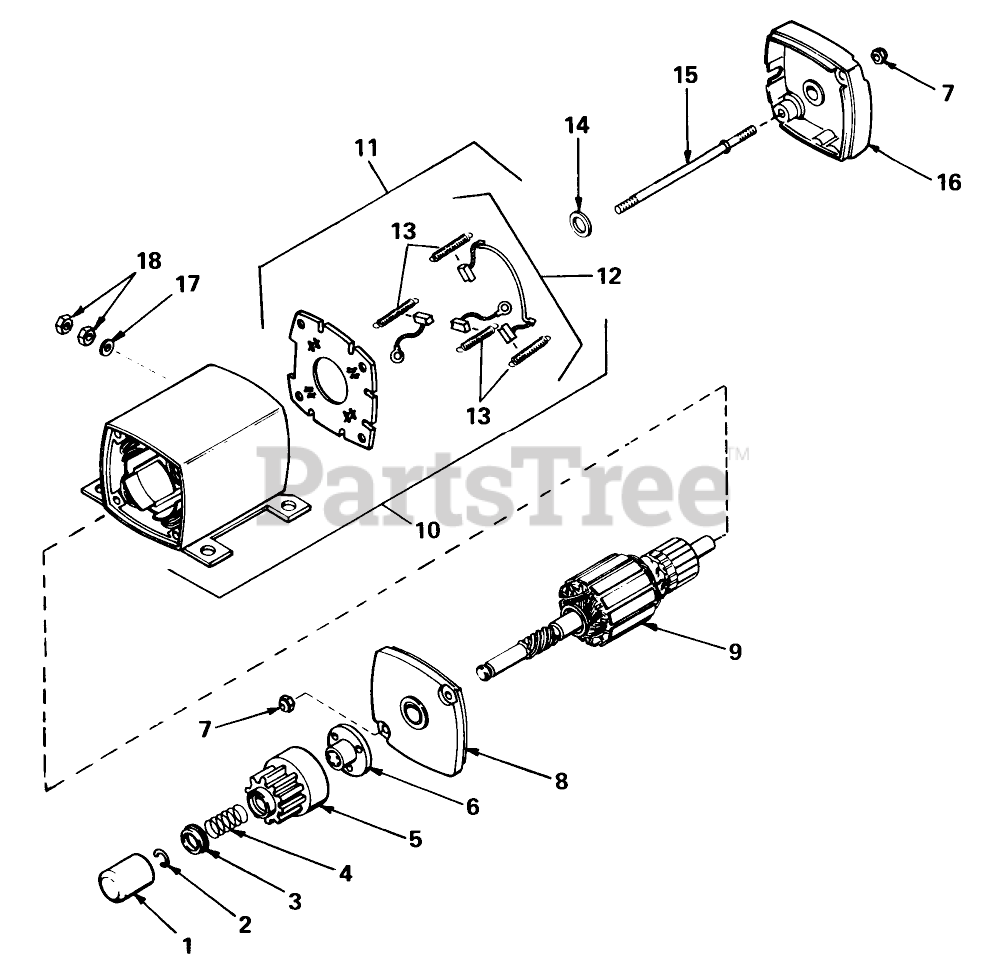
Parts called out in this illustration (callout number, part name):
1	Cover-Dust
2	Ring, Retainer
3	Retainer-Spring
4	Spring-Anti Drift
5	Gear
6	Nut-Engaging
7	Nut-Lock
8	Cap Assy., Drive End
9	Armature
10	Housing Assembly (Incl. Ref. #11)
11	Card Assy., Brush (Incl. No. 12)
12	Brush Spring Kit (Incl. 4 pcs. of #13)
13	1545D SUP TO W/3256
14	Washer-Thrust
15	Bolt
16	2035A67 WIZARD W/34
17	Washer
18	61710/VAR.HILLER AT
